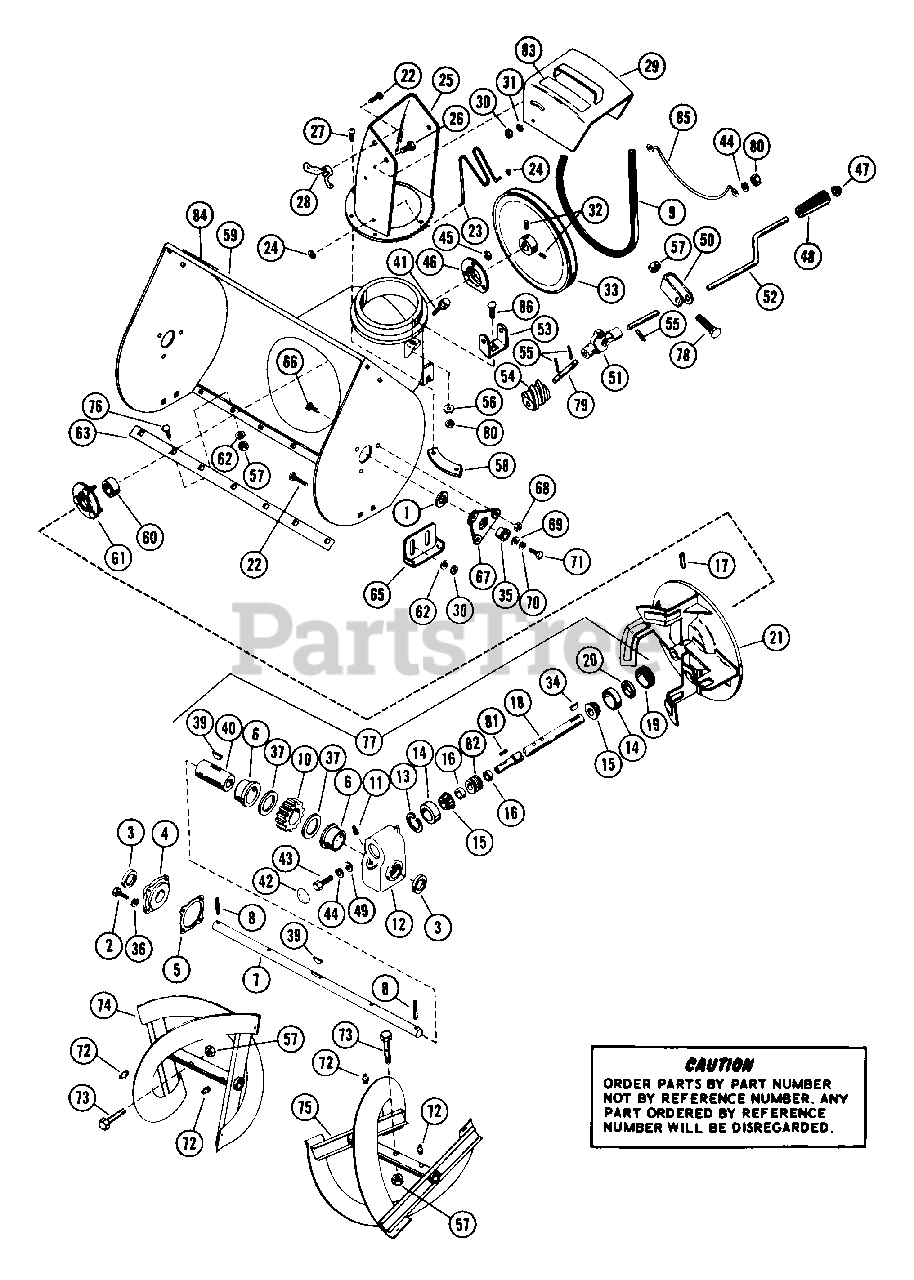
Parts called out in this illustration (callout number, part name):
1	WSHR-FL-STL 1.010X1.505X.062PL
2	BLT-HEX .25-20X.75 PL GR2
3	SEAL 1.625X2.125X.250
4	GEAR CASE COVER
6	BSHG-FLG .683X1.87X1.68X2.250
7	SHAFT, 32" RAKE - 1.00 DIA.
8	PIN-ROLL .188X1.50
10	WORM GEAR
11	PIPE PLUG
12	GEAR CASE - CAST IRON
13	RG-RTNG INT 1.781 HSG X.062
14	BRG-CUP 1.781X.475
15	BRG-CONE .750X.61
16	BSHG, SPCR .755X1.12X.50 PM
17	PIN-ROLL .313X1.75
18	SHAFT, WORM - 1.00 DIA.
19	ADJUSTMENT PLUG - 1" SHAFT
20	SEAL 1.000X1.312X.150
21	FAN, 12"
22	BLT-RDHDSQNK .38-16X.75 SHT PL
23	SAFETY WIRE
24	FASTENER
25	DISCHARGE CHUTE
26	BLT-HEX .38-16X.75 PL GR2
27	SCR-TAP 10-24X.375 CRPH 1A
28	WING NUT
29	SERVICE DEFLECTOR ASSM
30	NUT-LK-CTR .375-16 GR A PL
31	WSHR-LK .375X.115 HVY PL
32	SCR-SET .32-18X.38 SKHCUPNL OH
33	PLY-? 9.0X.75
34	KEY-WDRF .188X.875X.375 SAE11
35	BSHG-FLG 1.000X1.12X.62X1.50BR
36	WSHR-LK-EXT. 250 ID
37	WSHR-FL-STL 1.625X2.500X.012
39	KEY-WDRF .25X.875X.375 SAE A
40	GEAR CASE SHAFT
41	BLT-SCRHFWH .38-16X.75 PL
42	DUST CAP
43	BLT-HEX .31-18X.75 PL GR2
44	WSHR-LK .312X.097 PL HVY
45	NUT-LK-CTR .250-20 PL
46	BEARING FLANGE
47	CAP, 3/8 ROD YWZC
49	WSHR-FL-STL .328X1.0X.094
50	BRACKET
51	UNIVERSAL JOINT ASSEMBLY
52	CHUTE CONTROL CRANK
53	WORM CLEVIS
54	WORM GEAR
55	PIN-ROLL .125X.75
56	WSHR-LK .313X.062
57	NUT-LK .312-18 GR A PL
58	CHUTE CLAMP
59	BLOWER HOUSING 32 INCH
60	BRG-BALL .750X1.750X.50
61	BEARING FLANGE
62	WSHR-FL-STL .38X.875X.083 PL
63	SCRAPER BLADE
65	RUNNER
66	SCR-SLTR-SERNK .25-20X.62 PL
67	BEARING SUPPORT
68	NUT-LK-FLG .250-20 PL
69	WSHR-FL-STL .511X1.441X.125 PL
70	WSHR-LK .500X.151 HVY PL
71	BLT-HEX .50-13X1.00 PL GR2
72	SPIN DRIVE ZERK FITTING
73	SHEAR BOLT YWZC
74	RAKE, R.H. - 32"
75	RAKE, L.H. - 32"
76	BLT-RDHDSQNK .312-18X.62 PL
77	GEAR CASE - CAST IRON
78	BLT-RDHDSQNK .31-18X1.75 SHTPL
79	WORM SHAFT
80	NUT-HEX .312-18
81	KEY-SQ .188X1.0X.188 SAE 8630
82	STEEL WORM
83	CAUTION LABEL
84	ARIENS SCRIPT NAME PLATE
85	BELT FINGER
86	BLT-RDHDSQNK .31-18X.75 GR5 PL
